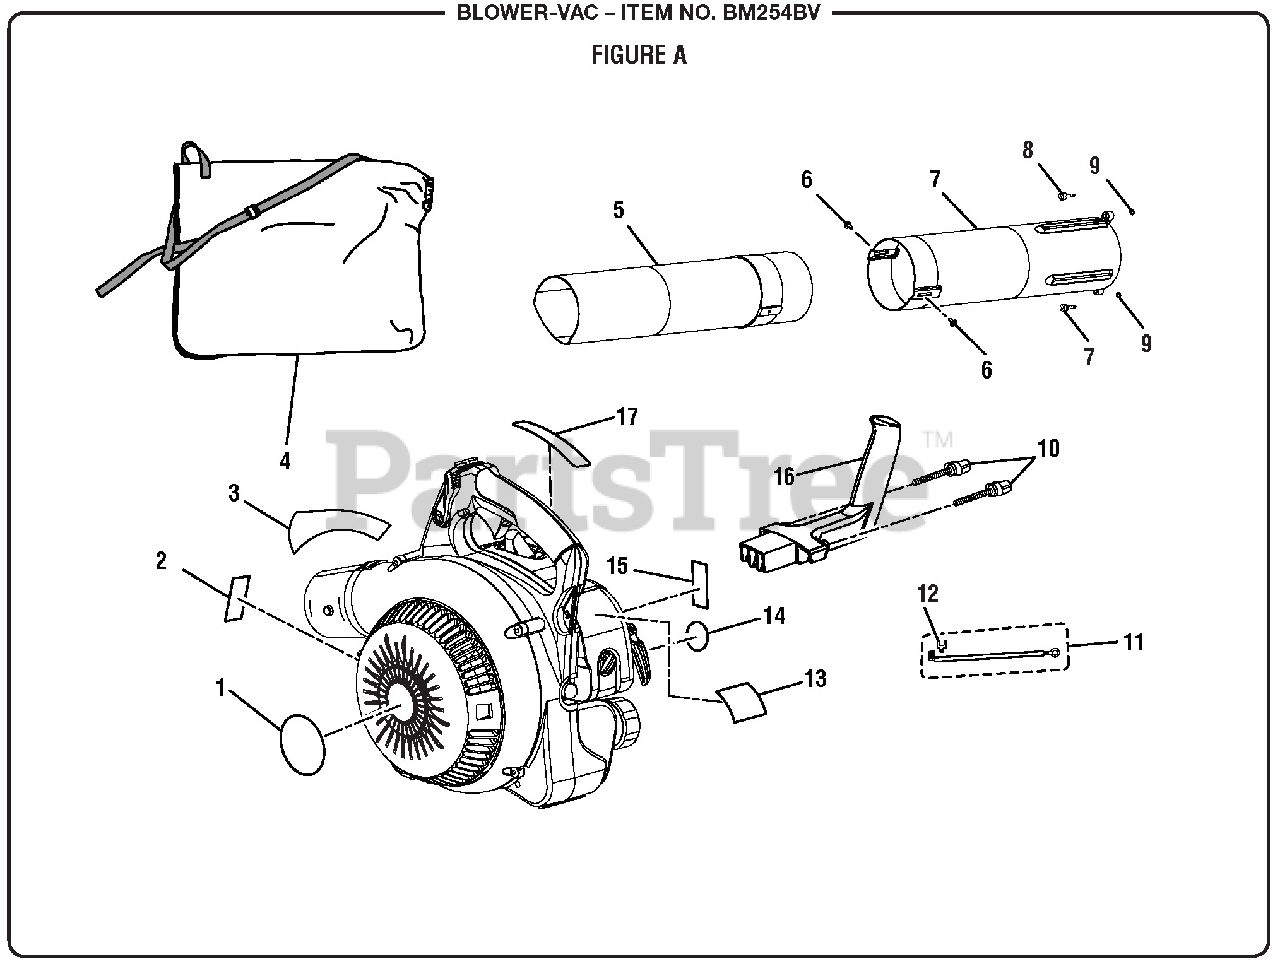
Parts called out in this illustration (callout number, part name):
1	Upper and Lower Blower Tube Assembly
2	Vacuum Bag Adaptor
3	Vacuum Door Label
4	Combustion Warning Label
5	3 in 1 Label
6	Vacuum Bag w/Shoulder Strap
7	Lower Vacuum Tube
8	Screw (10-14 x 1/2 in., T25 Torx T.F.)
9	Upper Vacuum Tube
10	Screw (1/4-20 x 3/4 in., Hex Hd.)
11	E-ring (Retaining Ring)
12	Vacuum Handle Knob
13	Ground Wire Kit
15	Starting Instructions Label
16	Starter Cover Label
17	Choke Label
18	Vacuum Handle
19	Warning Icon Label
